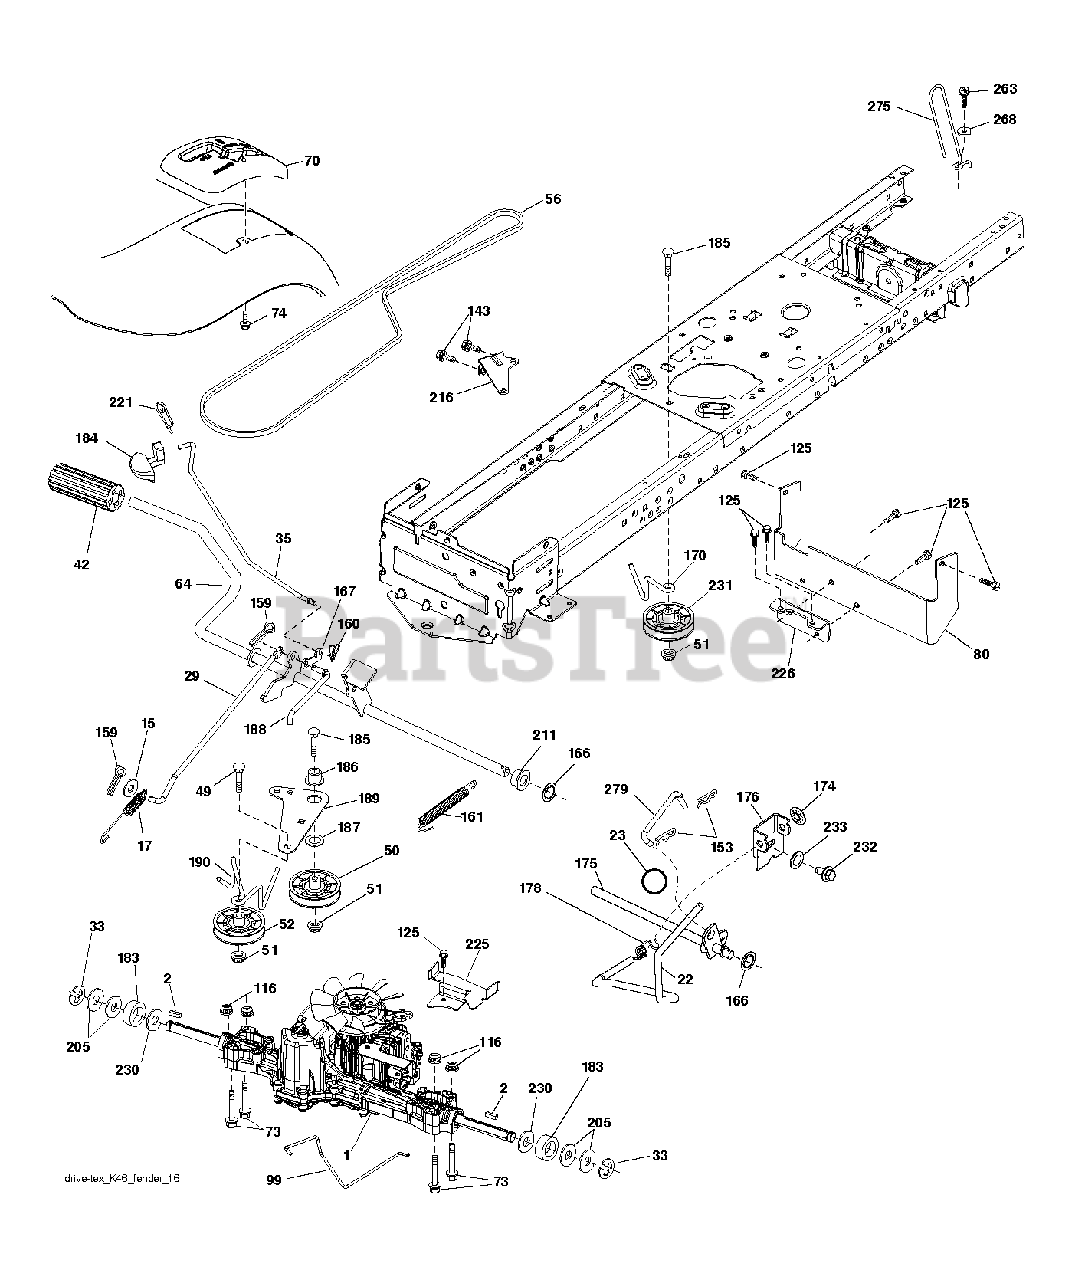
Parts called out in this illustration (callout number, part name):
17	SPRING.BRAKE.K46.GREEN
22	ROD.SHIFT.FENDER.TLT.2006
23	DASH.STEALTH.UPR.E.GT.SRV
29	ROD.BRAKE.K46
35	ROD, BRAKE, PARK
42	PEDAL COVER T
49	BOLT
50	IDLER.FLAT.910.OFFSET
51	NUT LOCK FLG 3/8-16 UNC
52	IDLER.V-GROOVE.910.OFFSET
64	SHAFT.ASM.PEDAL.BRAKE.
70	CONSOLE.SHIFT.STL.HYD.BLACK
74	SCREW.HI-LO.CONSOLE
80	STRAP TORQUE
99	ROD.SPRING.BYPASS.K46.LT.Z
116	NUT LOCK HEX FLANGE 5/16-18
125	SCREW
153	RETAINER M
159	COTTER PIN
160	RETAINER CLIP
161	SPRING, RETURN LT
167	LATCH.BRAKE.SPRING
170	KEEPER.CENTER SPAN.1.688
174	NUT.PUSH.500.2006
175	SHAFT.ASM.SHFT.T2.TLT
176	ARM.CLEVIS.ROD.SHIFT
178	SPRING.SHIFT.GT2006
184	HANDLE PARKING BRAKE
186	SPACER.RETAINER
187	WASHER 12/32X2X10GA
188	LINK.CLUTCH.GROUND.DRIVE
189	BELLCRANK.GROUND.DRIVE.TEX.
190	KEEPER.BELLCRANK.DRIVE
211	BUSHING.SHAFT.BRAKE.HAND
216	BRACKET.PULLEY.IDLER.W/TEX
221	RETAINER.SPRING.CLIP.H
225	KEEPER.BELT.TRANSAXLE.K46
226	BRACKET.MOUNT.TORQUE.K46.TLT
230	WASHER.HARDENED
231	IDLER.V-GROOVE.1.688.OFFSET
232	BOLT FIN HEX 7/16-14 X 1
233	WASHER SERRATED
263	SCREW, 3/8-16X3/4
268	WASHER
